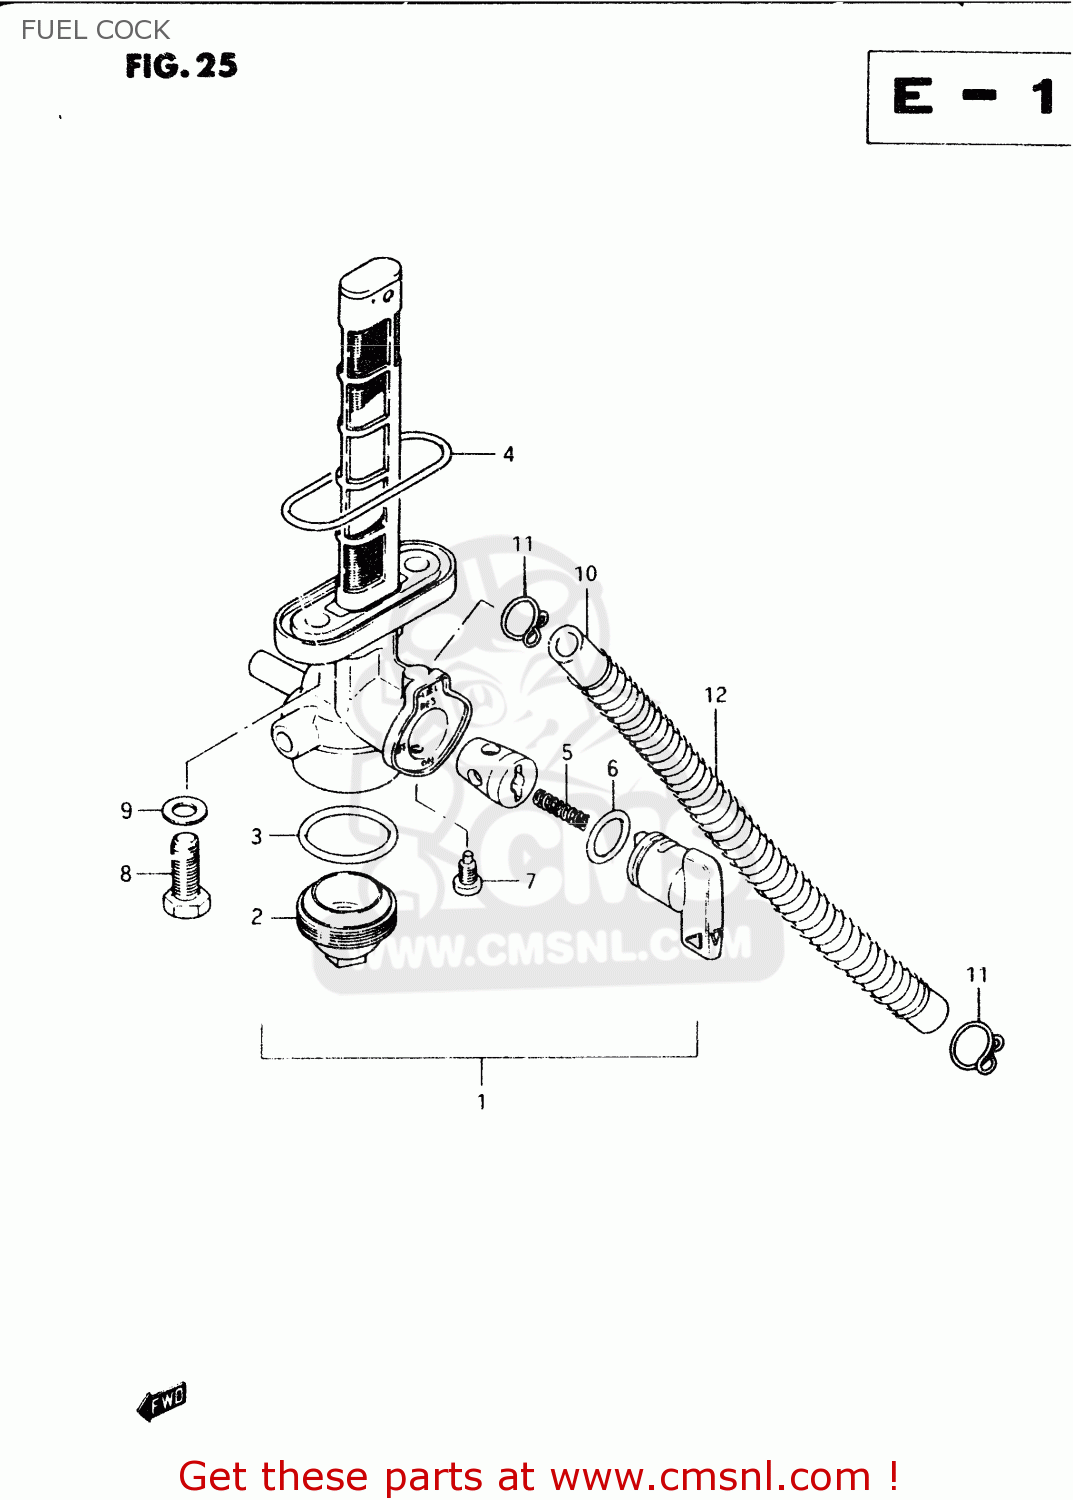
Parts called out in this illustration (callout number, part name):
1	COCK ASSY, FUEL
2	CUP,STRAINER
3	GASKET,FILTER (NAS)
4	O RING,FUEL COCK
5	SPRING
6	O-RING
7	SCREW
8	BOLT(6X20)
9	GASKET(6.4X11.5X0.8) (NAS)
10	HOSE
11	CLIP
12	SPRING
